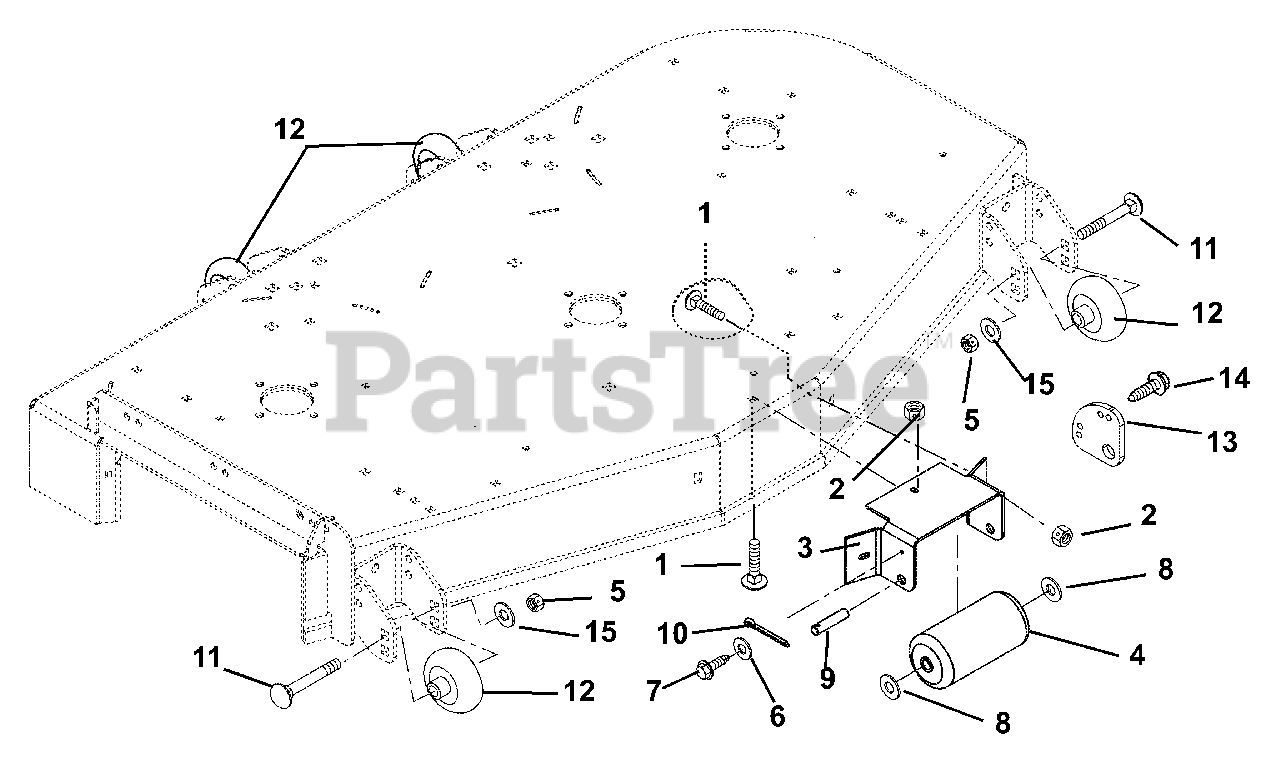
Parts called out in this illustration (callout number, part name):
1	@BLT-RDHDSQNK .38-16X1.00 G5YZ
1	@BLT-RDHDSQNK .38-16X1.25 G2YZ
2	@NUT-LK-TOP-FLG .38-16 YWZC
3	BRKT,ANTI-SCALP ROLL'R-ORANGE
5	@NUT-LK-NYL .50-13 YWZC
6	@WSHR-FL-STL.281X.62X.065 YWZC
7	SCR-TAP .25-20X.75 HWH TR YWZ
8	@WSHR-FL-STL.656X1.31X.095 YWZ
10	@PIN-CTR .25X2.00 YWZC
11	BLT-RDHDSQNK .50-13X5.00 GR5YZ
12	WHEEL, 3X5
13	ANTI-SCALP WASHER - ORANGE
14	SCR-TAP.250-20X.62 HWH BLK ZC
15	@WSHR-FL-STL.531X1.06X.095YWZC
